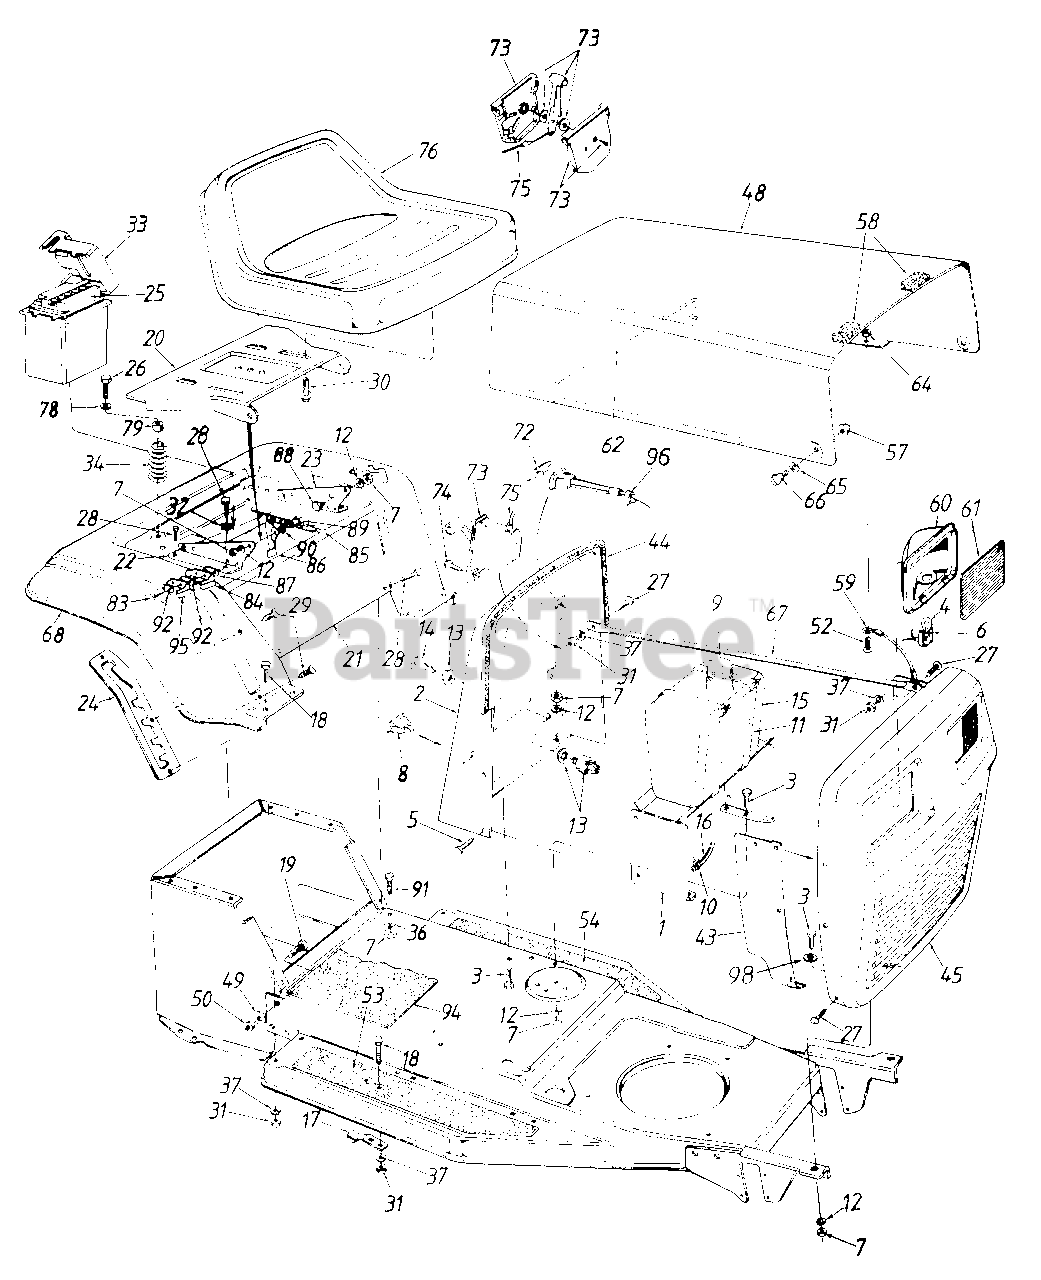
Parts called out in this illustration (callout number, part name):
1	Dash Panel Support Brkt.
4	Bulb
5	Hex AB-Tap Scr. 1/4 x .62"
6	Socket
7	Hex Nut 5/16-18 Thd.
8	Light Switch
9	Gas Cap
10	Hose Clamp
11	Cable Tie
12	L-Wash. 5/16" I.D.
13	Ignition Switch
14	Ignition Key
15	Fuel Tank
16	Gas Line 15" Long
17	Blade Brake Ass'y.
18	Carriage Bolt 1/4-20 x .62"
19	Ribbed Neck Bolt 3/8-24 x .8"
25	Battery
26	Hex Self-Tap Scr. 5/16-18 x 1.25" Lg.
27	Truss Mach. Scr. 1/4-20 x .62" Lg.
28	Hex AB-Tap Scr. 5/16 x .75" Lg.
29	Torx Mach. AB-Tap Scr. 1/4 x .62" Lg.
30	Hex Self-Tap Scr. 3/8-16 x .75" Lg.
31	Hex Nut 1/4-20 Thd.
32	External L-Wash. 5/16" I.D.
33	Battery Box w/Cover
34	Compression Spring
36	Bell-Wash. 5/16" I.D.
37	L-Wash. 1/4" I.D.
50	Hex L-Nut 3/8-24 Thd.
52	Truss Mach. Scr. #10-24 x .5" Lg.
53	Foot Pad - R.H.
54	Foot Pad - L.H.
57	Lock Nut 1/4-28 Thd.
58	Foam Strip
59	Hood Stop
60	Headlight Housing
61	Lens
62	Hood Spring
64	Hex Sems Nut #10-24 Thd.
65	Spr. Wash. .39" I.D. x .62" O.D.
66	Shld. Bolt
72	Choke Control
73	Throttle Control Box
74	Truss AB-Tap Scr. #10 x .5"
75	Throttle Wire (B&S)
76	Seat Assembly (Low Back)
78	Fl-Wash. .344" I.D. x .88" O.D.
79	Bushing
83	Hex Tap Scr.#8 x .5" Lg.
84	Safety Switch (Seat)
85	Ext. Spring 5.31" Lg.
86	Seat Lift Brkt.
87	Insulator Boss Plate
88	Shld. Bolt .437" Dia. x .162" Lg.
89	Shld. Bolt .437" Dia. x .268" Lg.
90	Spr. Wash. .445" I.D. x .75" O.D.
91	Hex Wash. Hd. Scr. 5/16-18 x .62" Lg.
92	Insulator Plate
94	Center Foot Pad
95	Safety Switch (Seat)
96	Retainer Clip
98	Fl-Wash. .34" I.D. x 1" O.D.
